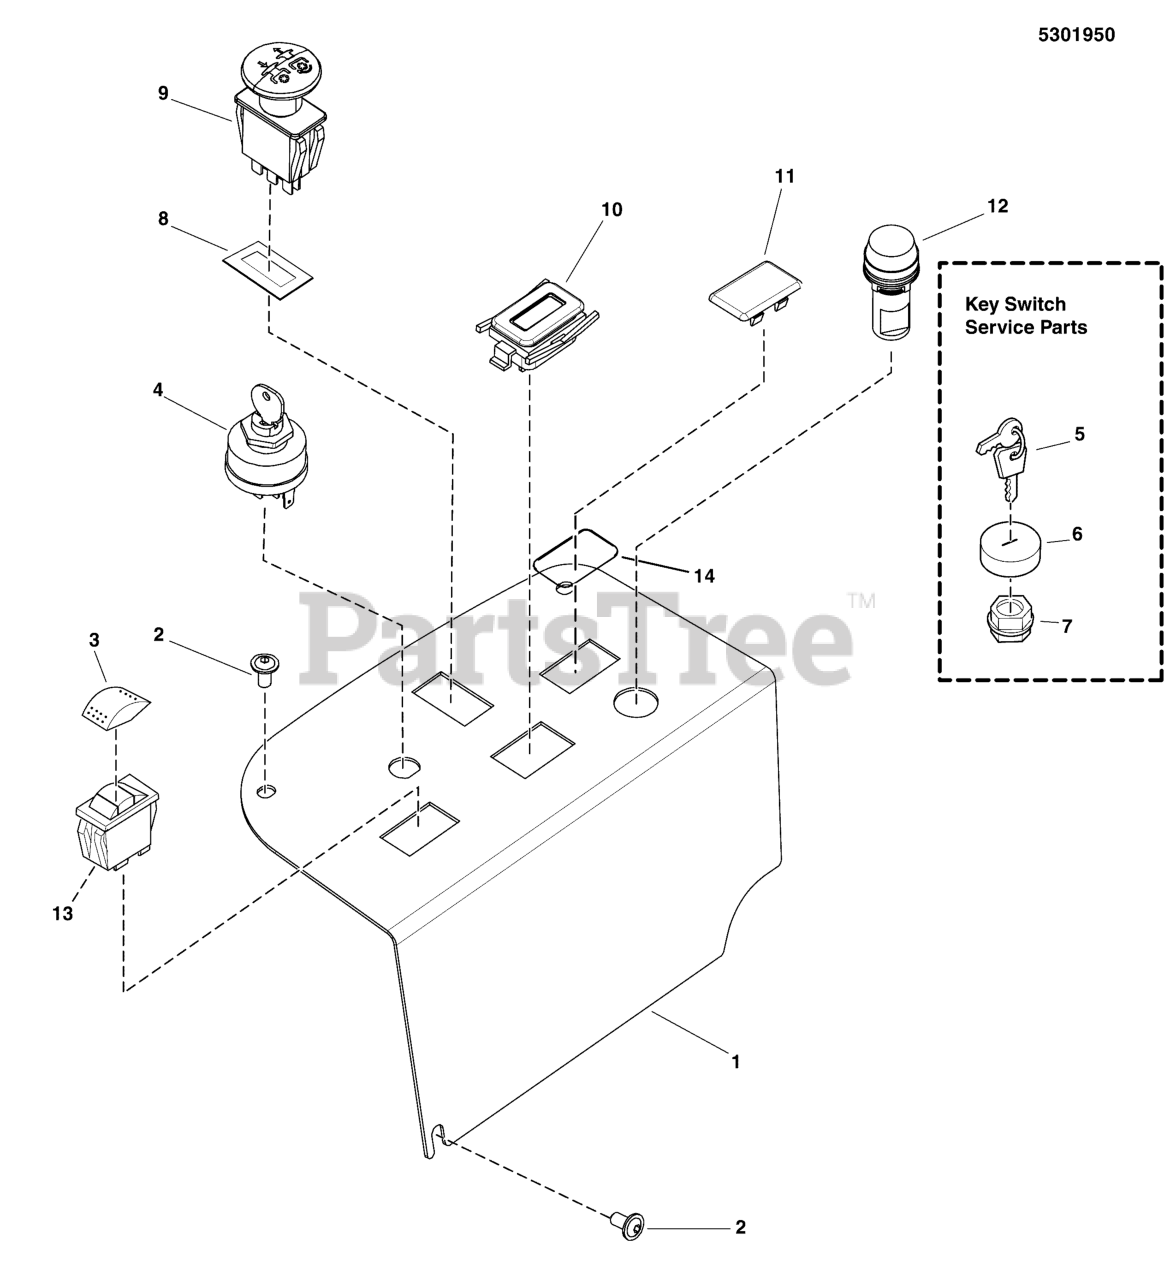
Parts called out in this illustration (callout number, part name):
1	PANEL, CONTROL, IS3100Z - BLK
2	SCREW, 1/4-20 X 1/2 ALLEN BH
3	ACTUATOR, ROCKER SWITCH - RED
4	SWITCH, IGNITION, 6 POST
5	KEY, IGNITION MOLDED SET
6	COVER, PLASTIC, SNAP ON
7	PLASTIC NUT
8	RING, SWITCH RETAINER
9	SWITCH, BLADE ENGAGEMENT
10	HOUR METER, ASSEMBLE
11	PLUG, .820X1.44 HOLE, BLACK PLASTIC
12	LAMP, MALFUNCTION INDICATOR
13	BODY, ROCKER SWITCH
14	O-RING, 7/8 ID X 1/16 W
